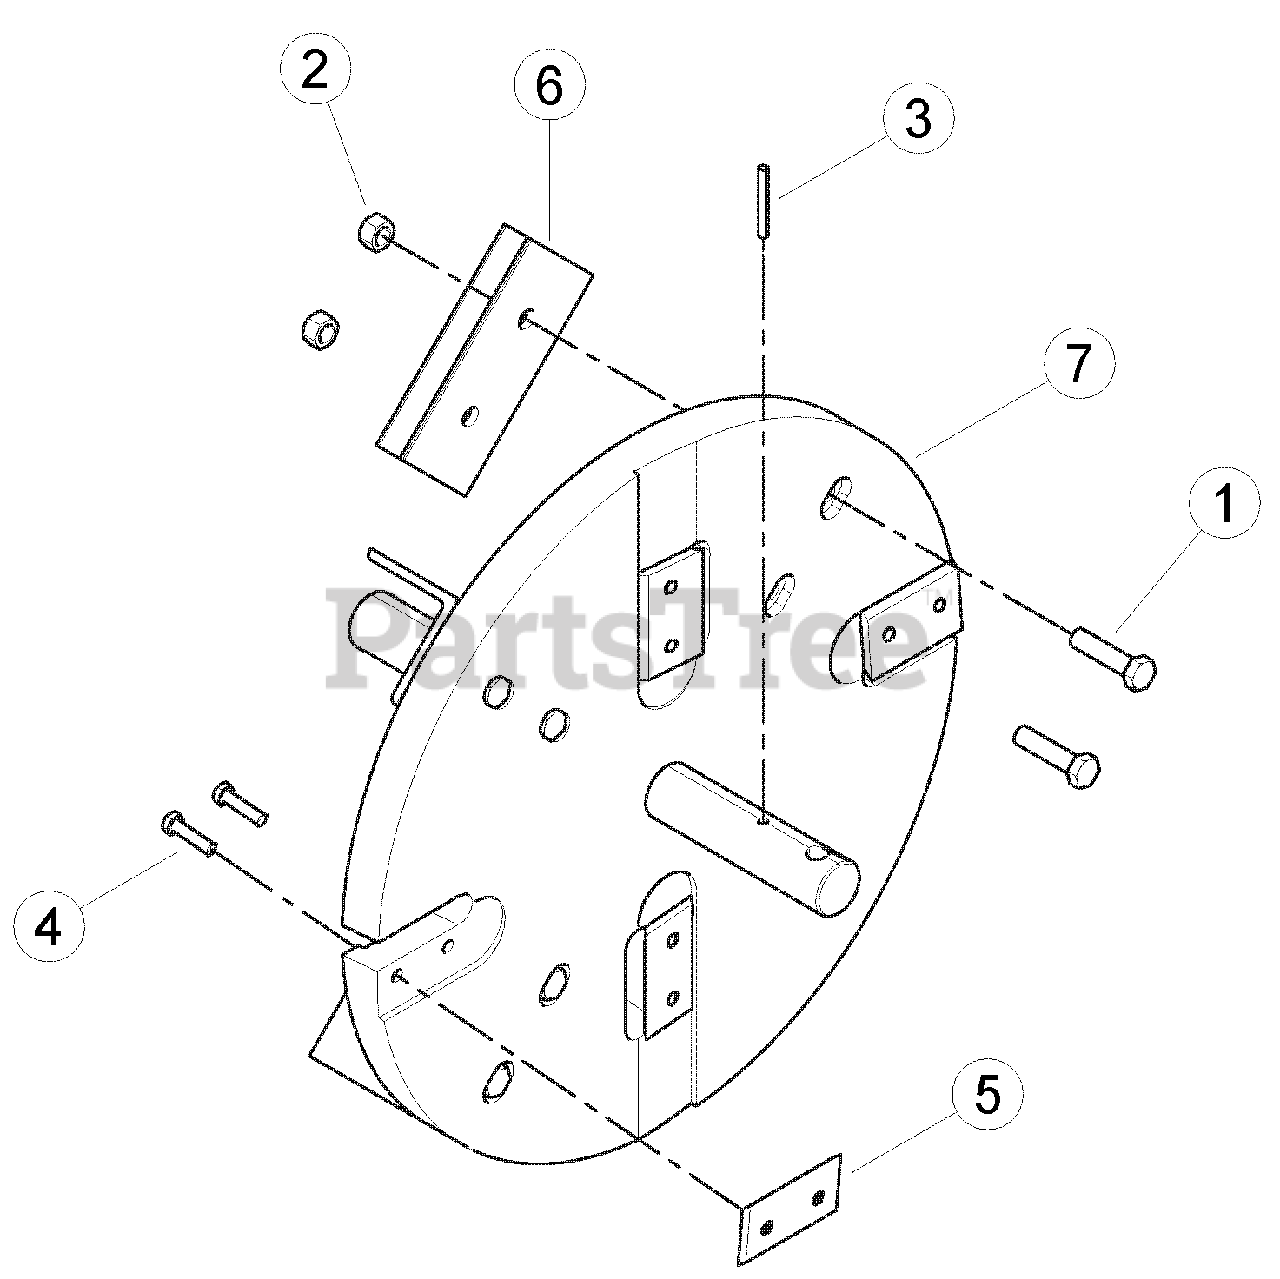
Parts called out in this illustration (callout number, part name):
1	BOLT, 1/2 X 2 HEX HD GR5 ZP
2	NUT, 1/2 CENTERLOCK GRB ZP
3	SPRING PIN, 1/4 X 2 LONG
4	BOLT, 5/16 X 1-1/4 HHD GR8 PATCH
5	BLADE, TWO EDGE TOOL STEEL (FOR SERVICE ORDER KIT #72493, CHIPPER BLADE REPLACEMENT)
5	KIT, CHIPPER BLADE
6	ANGLE, CHIPPER THROWER
7	WELDMENT, CHIPPER DISK
